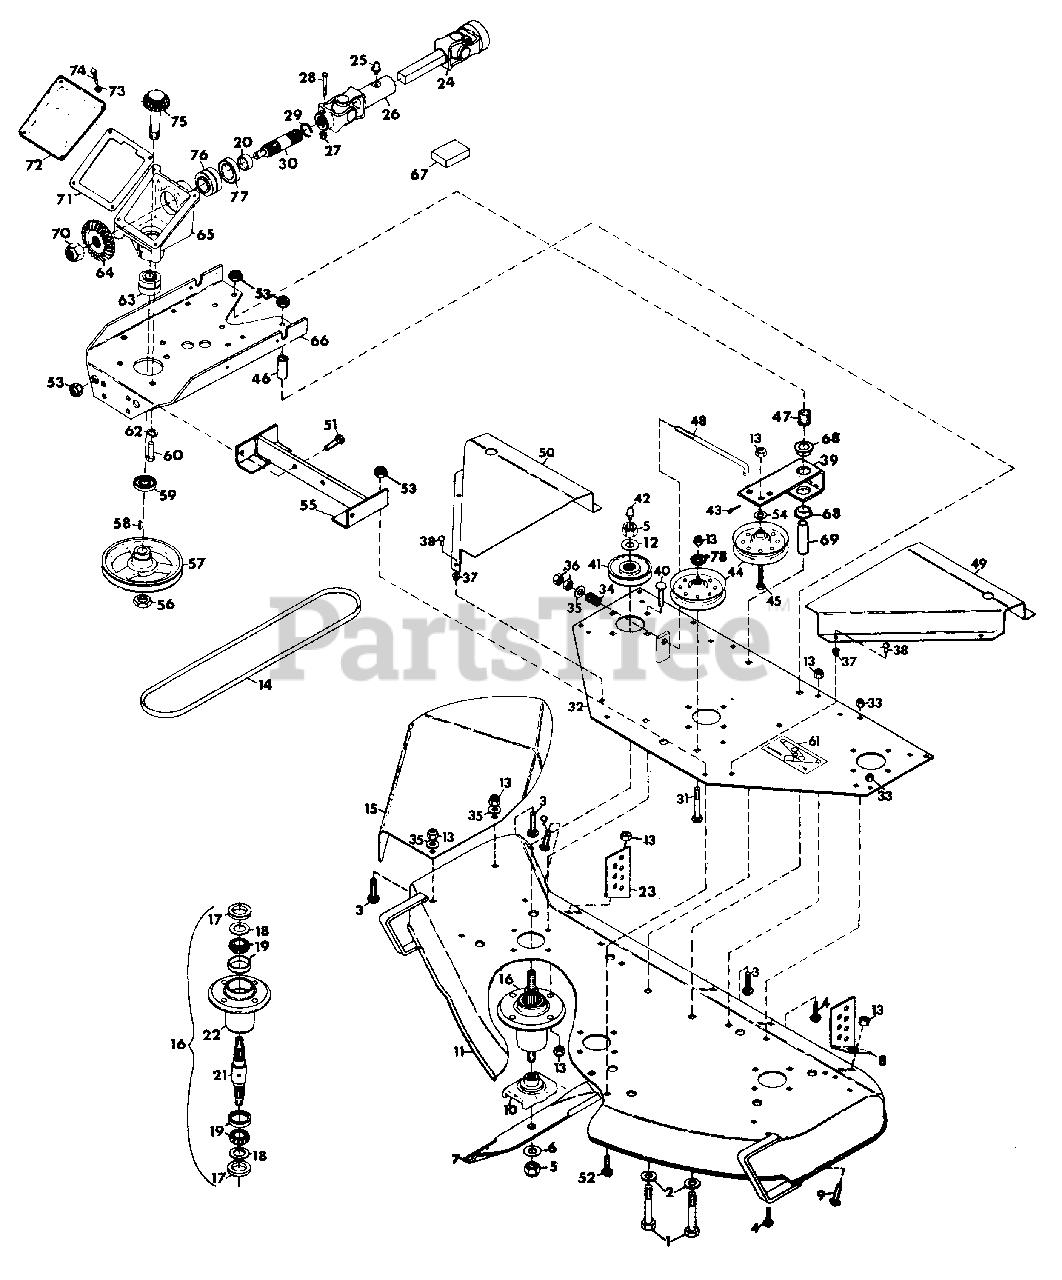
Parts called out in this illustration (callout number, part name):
1	BOLT, HEX 1/2-13X3.75
2	WASHER, FLAT .531X1.062X.095
3	BOLT, 3/8-16X.75 RD. HD. SQ. NK.
4	BOLT, 5/16-18X.75 RD. HD. SQ. NK.
5	NUT, LOCK 5/8-11
6	WASHER, FLAT .656X1.312X.095
7	BLADE
8	PLATE, REAR ADJUSTMENT
9	BOLT, HEX 3/8-16X1.25
10	CRADLE, BLADE
11	WELDMENT, PRO MASTER 50 INCH DECK
12	WASHER, FLAT .687X1.300X.122/.146
13	NUT, LOCK 3/8-16
14	BELT, V .500X.312X126.3
15	SHIELD, SAFETY EXTENSION 50 INCH MOWER
16	ASSEMBLY, SPINDLE
17	SEAL, STEEL
18	WASHER, FLAT .975X1.970X.030
19	ASSEMBLY, BEARING
20	SPACER
21	SHAFT, SPINDLE
22	HOUSING, BEARING
23	PLATE, REAR ADJUSTMENT
24	SHAFT, PROP. SQ. BAR
25	FITTING, LUBE 1/4-28
26	U-JOINT, FEMALE END
27	NUT, LOCK 1/4-20
28	BOLT, HEX 1/4-20X2
29	RING, RETAINING 1.000 SHAFT
30	SHAFT, DRIVE
31	BOLT, 3/8-16X1.75 RD. HD. SQ. NK.
32	WELDMENT, DECK SUPPORT PLATE
33	NUT, LOCK 5/16-18
34	SPRING, COMP. TYPE 1X.78X338 LB/IN
35	WASHER, FLAT .406X.812X.065
36	NUT, HEX 3/8-24
37	GROMMET, PLASTIC
38	SCREW, MACH. 1/4-20X.5
39	ARM, IDLER PIVOT
40	BOLT, 3/8-16X1.25 RD. HD. SQ. NK.
41	SHEAVE, SPINDLE
42	FITTING, LUBE 1/8(LEFT AND RIGHT SPINDLE)
42	FITTING, LUBE .125 EXT.(CENTER SPINDLE)
43	PIN, COTTER 3/32X1.00
44	SHEAVE, IDLER
45	BOLT, HEX 3/8-16X2
46	SPACER, .510X.840X2.43
47	SPRING, COMP.
48	ROD, IDLER
49	COVER, PULLEY L.H.
50	COVER, PULLEY R.H.
51	BOLT, HEX 1/2-13X1.375
52	BOLT, HEX 1/2-13X1.25
53	NUT, LOCK 1/2-13
54	SPACER, IDLER .406X.750X.188
55	BRACKET, HEIGHT ADJUSTMENT
56	NUT, JAM 3/4-10 HEX HEAVY
57	SHEAVE, 1/2X6.50
58	KEY, WOODRUFF .188X.625 HARD
59	SEAL, OIL 1.250X1.686X.313
60	BOLT, HEX 1/2-13X1.00
61	DECAL, BELT INSTALLATION
62	WASHER, LOCK 1/2
63	ASSEMBLY, BEARING .750X1.781X1.499
64	GEAR, BEVEL
65	CASTING, GEAR BOX
66	SUPPORT, GEAR HOUSING
67	KIT, REPAIR UNIVERSAL JOINT ROCKWELL STD.
67	KIT, REPAIR UNIVERSAL JOINT NEAPCO 1605X
68	BUSHING, NYLON .760X1.00X.600
69	SPACER
70	NUT, LOCK 3/4-10
71	GASKET, GEAR HOUSING
72	COVER, GEAR HOUSING
73	WASHER, LOCK 1/4
74	BOLT, HEX 1/4-20X.50
75	SHAFT, GEAR PINION
76	ASSEMBLY, BEARING 1.000X1.980X1.243
77	SEAL, OIL 1.250X1.987X.250
78	WASHER, FLAT .438X1.000X.083
NS	ASM, DRIVE 50" MOWER
NS	DECAL, DANGER HAND
NS	DECAL, DANGER FOOT
NS	DECAL, WARNING EYE
NS	DECAL, PRO MASTER-50 MOWER
